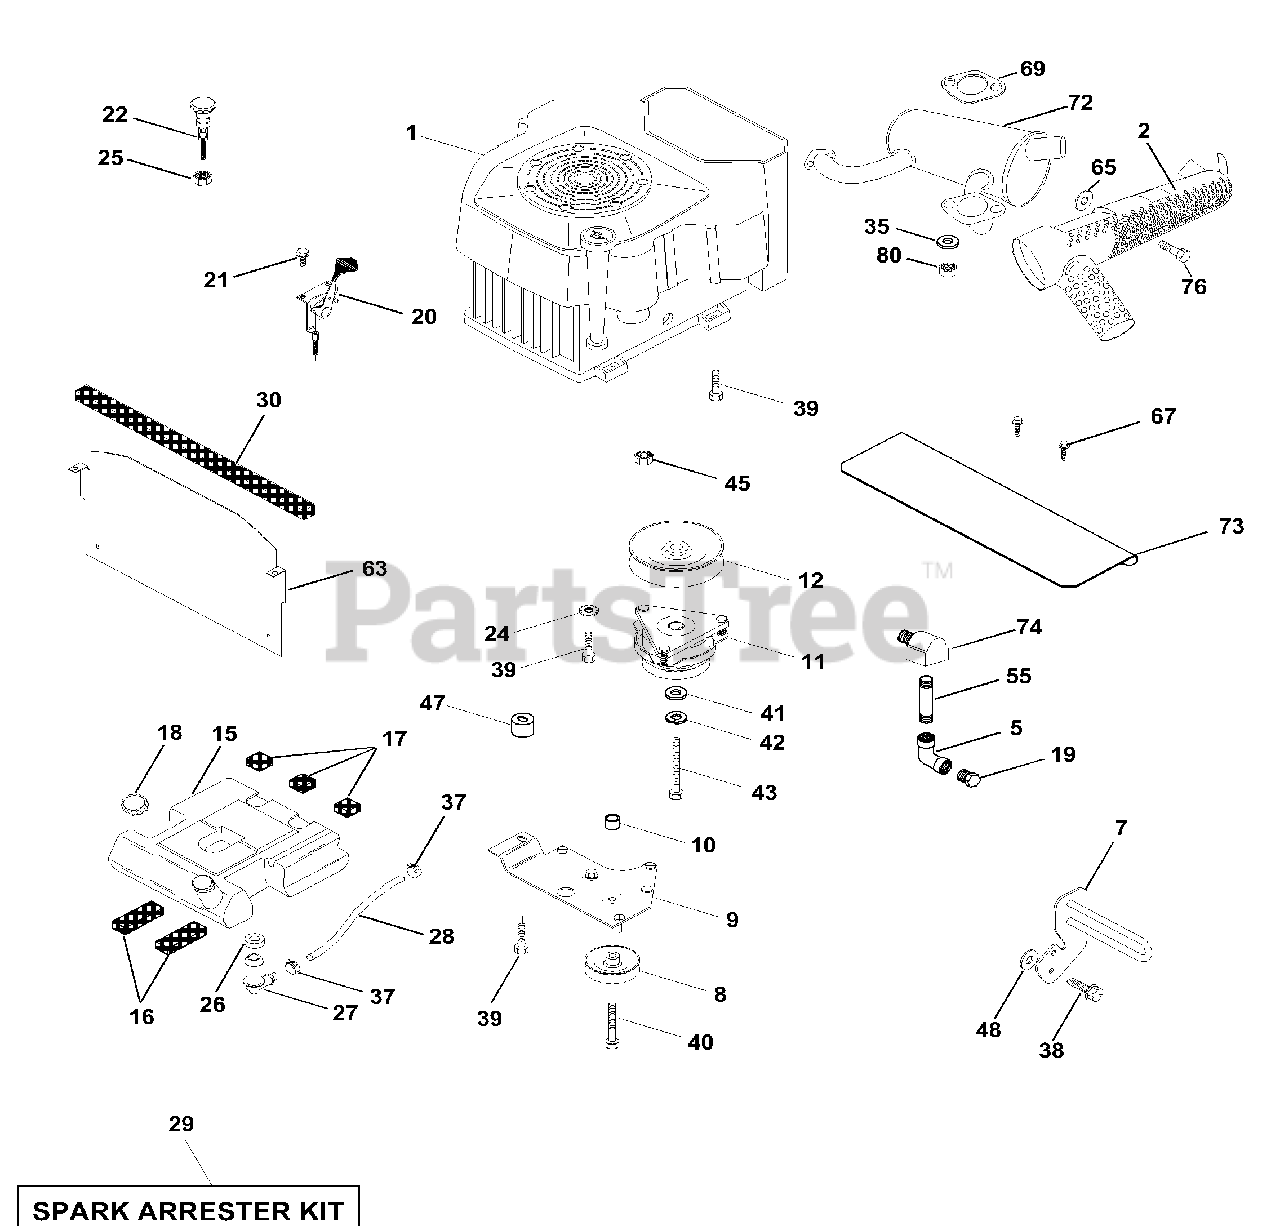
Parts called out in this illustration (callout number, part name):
2	Muffler Side
5	Elbow STD 90 Degree 3/8-18 NPT
7	Muffler Assembly Guard
8	Pulley V-Idler
9	Keeper Asm Belt Engine VGT 96
11	Clutch Electric
12	Pulley Engine VGT Elect Clutch
15	Tank Fuel Rear
16	Pad Spacer
17	Pad Spacer
18	Cap Asm Fuel W/Sym Vented
19	Plug Oil Drain
20	Control Throttle
21	Screw Hex Thd Cut 1/4-20 X 5/8
22	Control Choke
24	Washer Ext Tooth 3/8
25	Nut Keps 3/8 - 24 UNF
26	Bushing
27	Stem Tank Fuel
28	Fuel Line
29	Spark Arrester Kit
30	Extrusion Hood
35	Washer Split
37	Clamp Hose
38	Screw 3/8-16 x 1-1/4
39	Screw TT 3/8-16 x 2-1/4 UNC
40	Screw TT 3/8-16 x 4 UNC
41	Washer 1-1/2 OD X 15/32 ID X .250
42	Washer Lock 7/16
43	Bolt Hex 7/16-20 X 4-1/4 Ga 5
45	Nut Flange M8 1.25
47	Spacer Engine
48	Washer 13/32 x 1-1/4 x 7 Ga.
55	Nipple, Pipe 4-1/2"
63	Shield, Heat VGT YP/Husq.
65	Washer 13/32 x 1 x 14 Ga.
67	Screw 5/16-18 x 3/4
69	Gasket
72	Muffler Pre CV25
73	Shield Heat Muffler
74	Elbow Street Brass
76	Screw 3/8-16 x 3/4
80	Nut Flange M8 1.25
